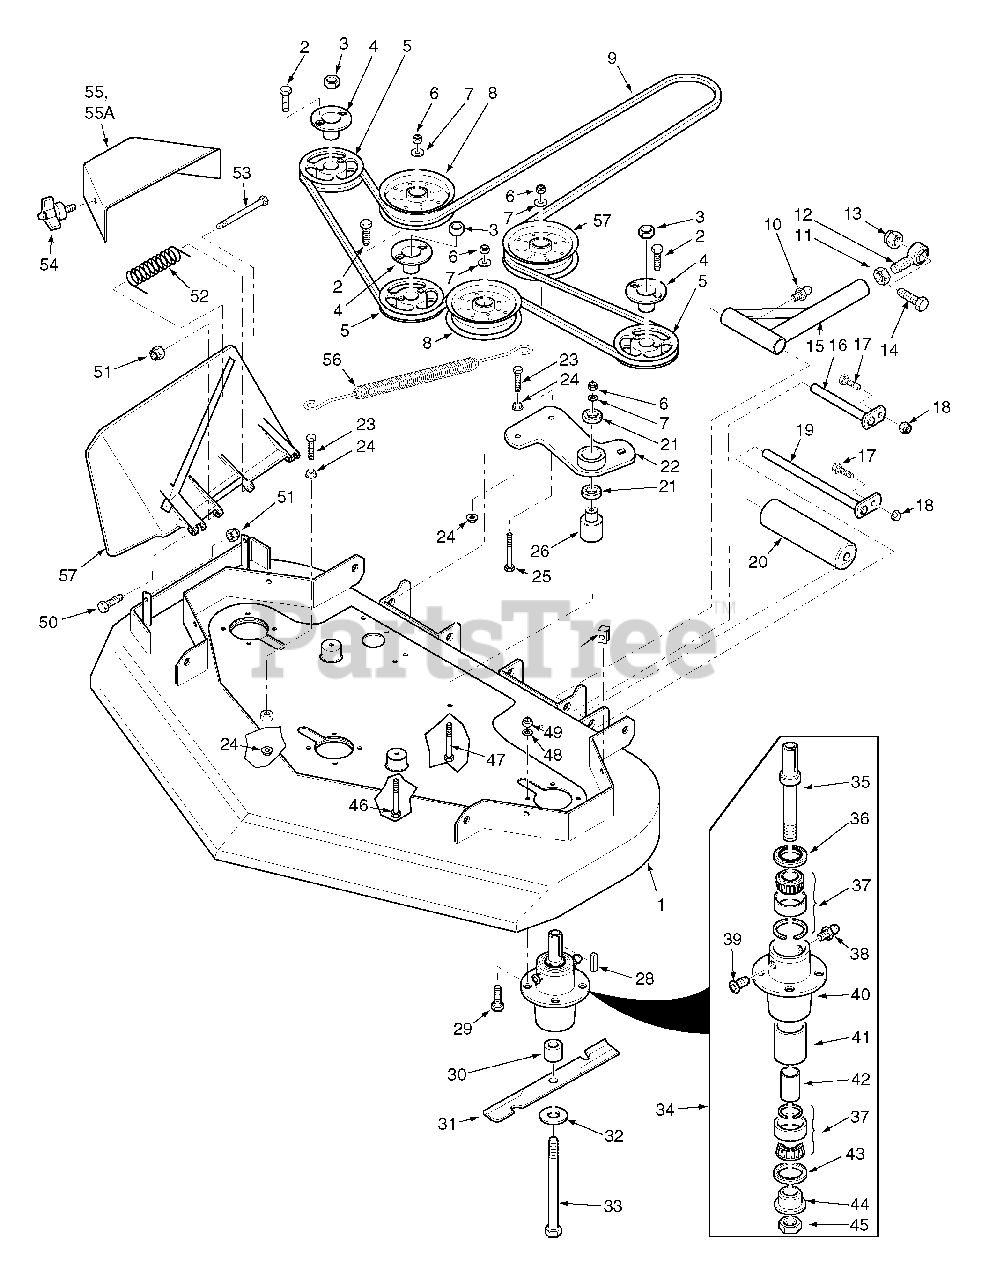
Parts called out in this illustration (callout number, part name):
1	Cutter Deck
2	Bolt, Hex Head 1/4-20 x 1"
3	Nut, 5/8-11
4	Tapered Hub, 1.125" Bore
5	Pulley, 4.75 O.D. (42")
6	Nut, Elastic Stop 3/8-16
7	Flatwasher, 3/8-.391 x .938 x .105
8	Pulley, 5" Idler
9	Belt, Cutter Deck (42")
10	Grease Fitting 1/4-28 Self Tapping
11	Nut, 1/2-20 UNF
12	Rod End, 1/2-20 RH Thread
13	Nut, Elastic Stop 1/2-13
14	Bolt, Hex Head 1/2-13 x 4"
15	Push Arm Assembly
16	Rod Weldment, Push Arm
17	Bolt, Hex Head 5/16-18 x 1"
18	Nut, Serrated Flange 5/16-18
19	Shaft Weldment, Guide Roller
20	Roller
21	Bearing
22	Idler Arm Assembly
23	Bolt, Hex Head 3/8-16 x 1-1/2" Gr. 8
24	Nut, Serrated Flange 3/8-16
25	Bolt, Hex Head 3/8-16 x 3"
26	Pivot, Idler
27	U-Nut, 3/8-16
28	Key, 1/4 x 1/4 x 1"
29	Bolt, 5/16-18 x 1-3/4" Gr. 8
30	Spacer, Spindle
31	Cutter Blade, 14-3/4"
32	Flatwasher, 5/8-.688 x .75 x .134 HD
33	Bolt, Hex Head 5/8-11 x 9-1/2"
34	Spindle Assembly
35	Shaft, Cutter Spindle
36	Seal, Top
37	Bearing Assembly
38	Grease Fitting
39	Relief Fitting, Tapered Spindle
40	Spindle Housing
41	Spacer, Outside
42	Spacer, Inside
43	Seal, Bottom
44	Spindle Bushing, Bottom
45	Nut, Special 1 - 1/16-18
46	Bolt, 3/8-16 x 4-1/2"
47	Bolt, 3/8-16 x 3-1/2"
48	Lock washer, 5/16"
49	Nut, Elastic Stop 5/16-18 Gr. 8
50	Bolt, 5/16-18 x 1-1/2"
51	Nut, Elastic Stop 5/16-18
52	Spring, Discharge Chute
53	Bolt, Hex Head 5/16-18 x 4-3/4"
54	Knob w/stud, 3/8-16 x 1-1/4"
55	Belt Cover
56	Spring
57	Pulley, 5" Idler
58	Discharge Chute
